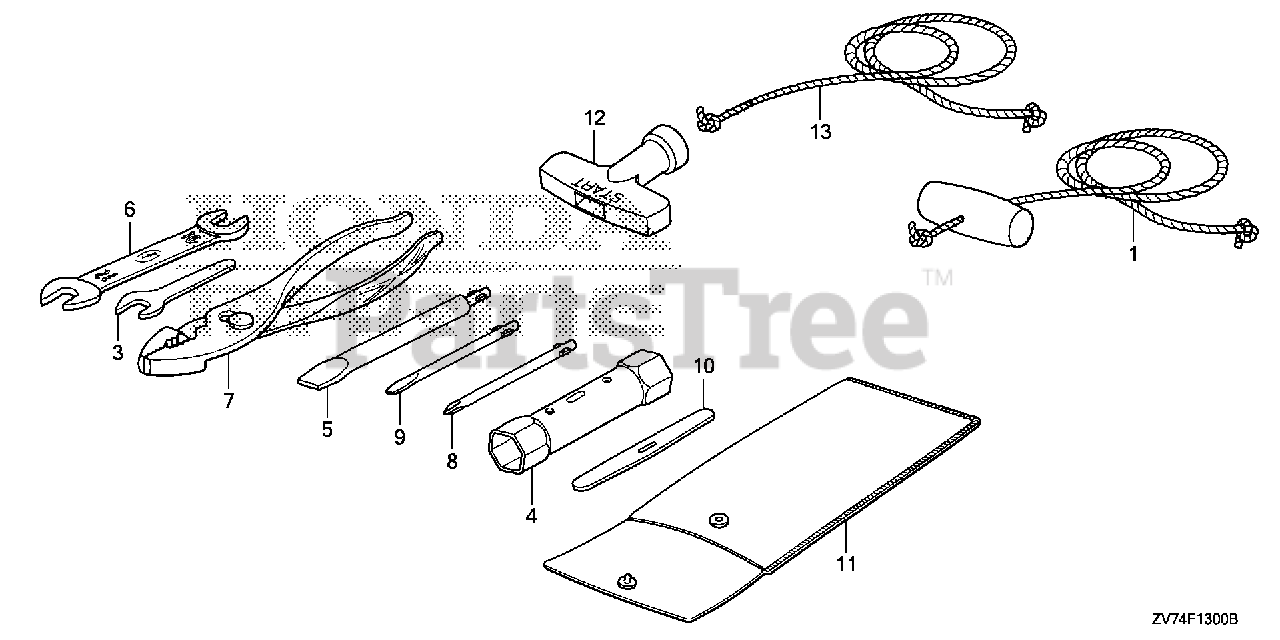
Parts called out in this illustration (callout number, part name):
1	ROPE, STARTER
3	SPANNER (8MM) (NOT AVAILABLE)
4	WRENCH, BOX (P18X19) (NOT AVAILABLE)
5	SCREWDRIVER, CHECK BOLT
6	SPANNER (10X12)
7	PLIERS (135) (KOWA)
7	PLIERS (135)
8	DRIVER 1, PLUS SCREW (NO.2)
9	DRIVER 3, MINUS SCREW (NO.2)
